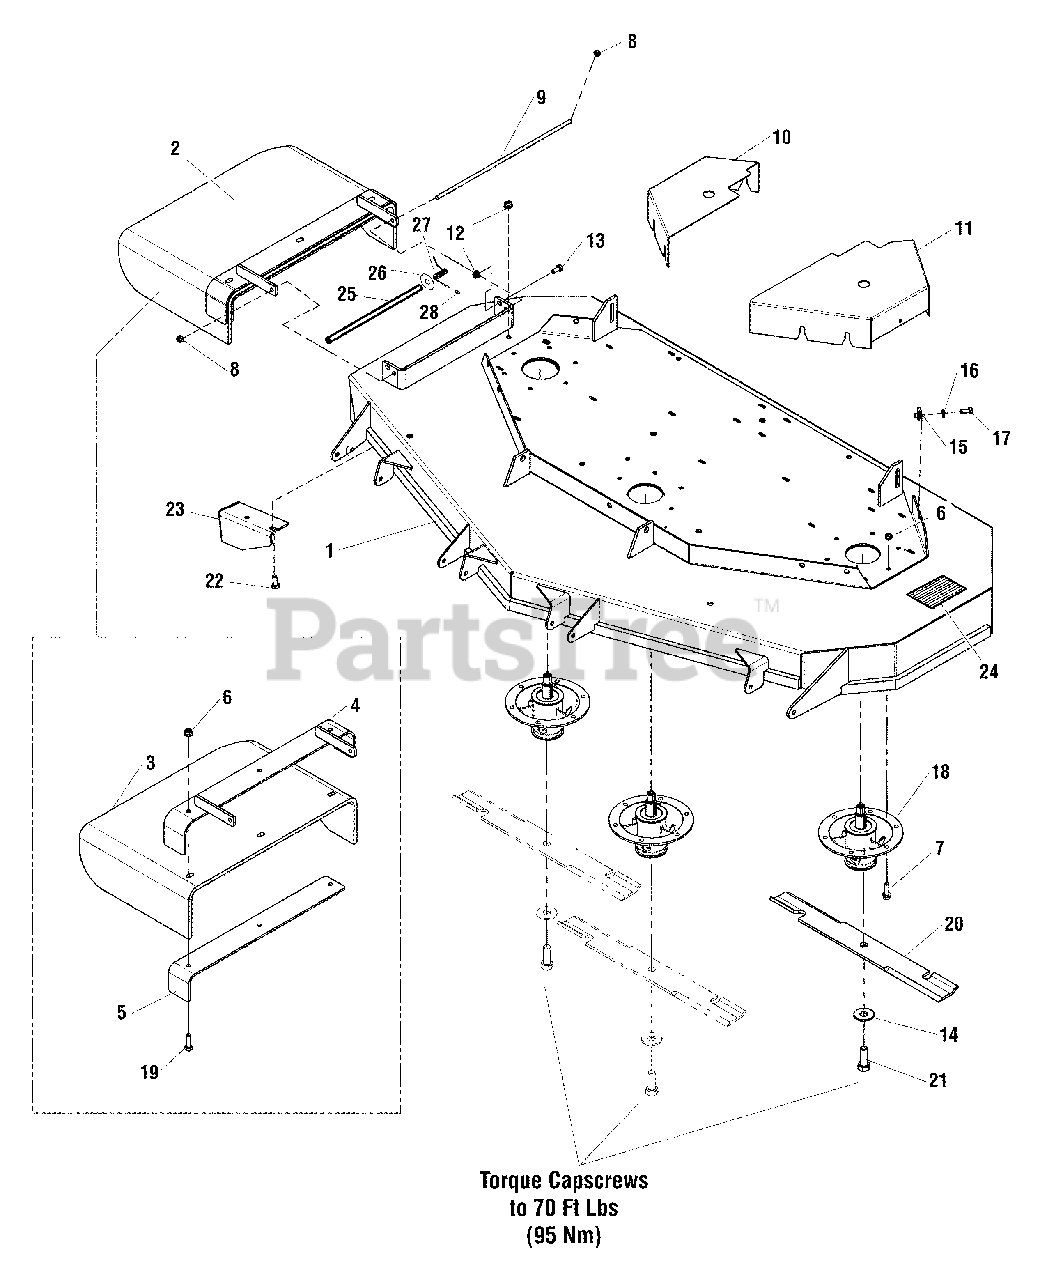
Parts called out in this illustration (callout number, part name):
1	DECK SHELL W/DECALS, 61" SIDE DISCHARGE
2	CHUTE ASSEMBLY, 61"
3	CHUTE, DISCHARGE, RUBBER, 61/72"
4	WELD, FRAME, CHUTE, 61
5	SUPPORT, DISCHARGE CHUTE - BLK
6	NUT, 3/8-16 HEX NYLOCK FLANGE
7	BOLT, 3/8-16 X 1-1/4" GD5
8	NUT, 5/16-24 HEX NYLON LOCK
9	ROD MOUNT, CHUTE 61"
10	GUARD, 61", RH
11	GUARD, 61" - LH
12	NUT, 5/16-18 HEX NYLOCK FLANGE
13	SCREW-HEX WZ LOCK FLNG 5/16-18X0.750BLK
14	WASHER, 5/8" GRADE 8, YZ
15	BODY CLIP, 5/16-18 X 1/2" DEEP
16	WASHER, 5/16" GD.9 FLAT
17	BOLT, 5/16-18 X 3/4" GD5
18	ASSM, SPINDLE, CAST IRON
19	BOLT, 3/8-16 X 1 1/2"
20	BLADE, 21"
21	BOLT, 5/8-11 X 1-3/4" GD8
22	BOLT, 5/16-18 X 3/4, CARRIAGE
23	PLATE, DEFLECTOR - BLK
24	SAFETY WALK, 9.75 X 6.00
25	TORSION SPRING SPACER
26	WASHER, 5/16 FENDER
27	TORSION SPRING
